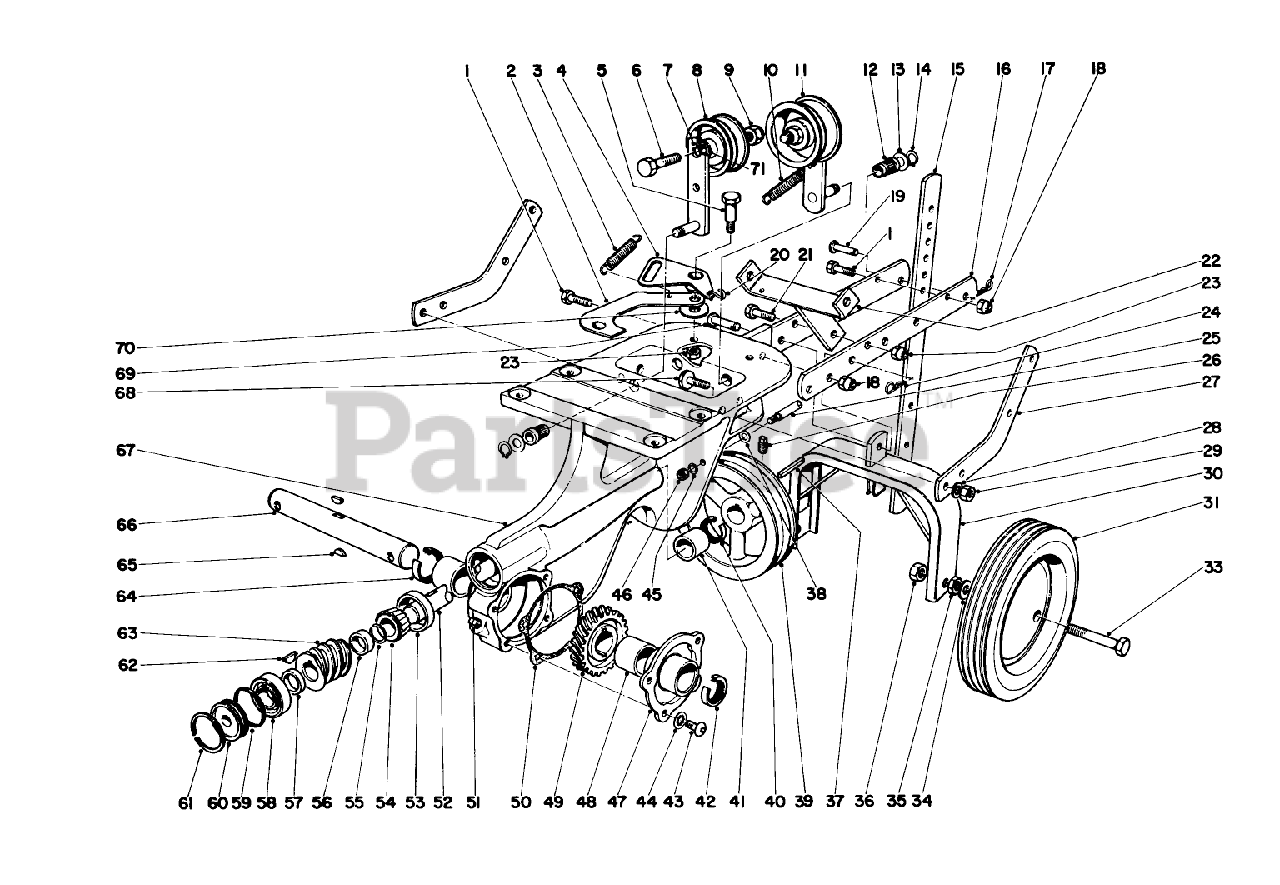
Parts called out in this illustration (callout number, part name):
1	SCREW-HH
5	SCREW-SHOULDER, HH
6	SCREW-HH
9	NUT-LOCK, CONE
11	PULLEY-IDLER
13	Washer
14	RING-RETAINING, EXT
16	Drawbar
17	PIN-COTTER, HAIR
18	NUT-LOCK, CONE
21	SCREW-HH
22	Support
23	NUT-LOCK, CONE
24	PIN-COTTER, HAIR
26	SCREW-SET, HSH
27	Handle Bracket
28	WASHER-LOCK
29	NUT-HEX
30	Wheel Bracket
34	WASHER-FLAT
35	NUT-JAM
37	KEY-SQUARE
38	WASHER-FLAT
42	SEAL-OIL
43	SCREW-HSBH
44	WASHER-LOCK
45	WASHER-LOCK/EXT
46	NUT-JAM
48	Bearing
50	GASKET
51	PLUG-PIPE, SQH
54	3/4 ROLLER BRG CONE
55	RETAINER RING
58	.750 BALL BEARING
59	O-RING
61	INTRNL RETAINING RING
62	KEY-WOODRUFF
64	SEAL-OIL
65	KEY-WOODRUFF
67	Chassis
68	Leveler Hd.
